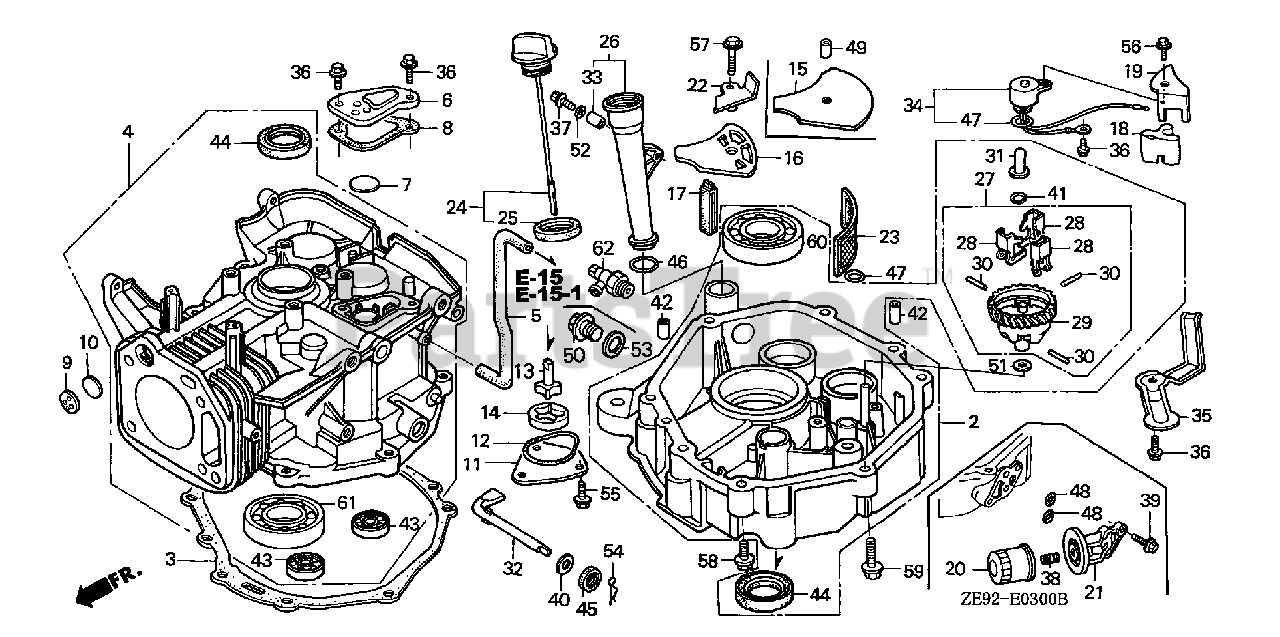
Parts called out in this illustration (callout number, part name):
2	PAN ASSY., OIL
3	GASKET, OIL PAN
4	CYLINDER ASSY.
5	TUBE, BREATHER
6	CAP, BREATHER CHAMBER
7	VALVE, BREATHER
8	GASKET, BREATHER CAP
9	PLATE, ONE-WAY VALVE
10	VALVE, ONE-WAY
11	COVER, OIL PUMP
12	O-RING, PUMP COVER
13	ROTOR (INNER)
14	ROTOR, OIL PUMP (OUTER)
16	PLATE, OIL FILTER
17	RUBBER, OIL RETURN
18	STOPPER, OIL
19	PLATE, OIL STOPPER
22	PLATE, SUCTION
23	SCREEN, OIL FILTER
24	CAP ASSY., OIL FILLER
25	GASKET, OIL FILLER CAP
26	EXTENSION, OIL FILLER
27	GOVERNOR ASSY.
28	WEIGHT, GOVERNOR
29	HOLDER, GOVERNOR WEIGHT
30	PIN, GOVERNOR WEIGHT
31	SLIDER, GOVERNOR
32	SHAFT, GOVERNOR ARM
33	COLLAR, EXTENSION
34	SWITCH, OIL LEVEL
35	PROTECTOR, SWITCH
36	BOLT, FLANGE (6X12) (CT200)
37	BOLT, FLANGE (6X35) (CT200)
40	WASHER, THRUST (8.1MM)
41	CLIP, GOVERNOR HOLDER
42	PIN, DOWEL (8X12)
43	BEARING, RADIAL BALL (6202)
44	OIL SEAL (35X52X8)
45	OIL SEAL (8X14X5)
46	O-RING (22.1X2.2)
47	O-RING (11.8X2.4)
50	BOLT, DRAIN PLUG (20MM)
51	WASHER, PLAIN (6MM)
52	WASHER, PLAIN (6MM)
53	WASHER, DRAIN PLUG (20MM)
54	PIN, LOCK (10MM)
55	BOLT, FLANGE (6X12)
56	BOLT, FLANGE (6X16)
57	BOLT, FLANGE (6X25)
58	BOLT, FLANGE (8X40)
59	BOLT, FLANGE (8X60)
60	BEARING, RADIAL BALL (6207)
61	BEARING, RADIAL BALL (6207)
